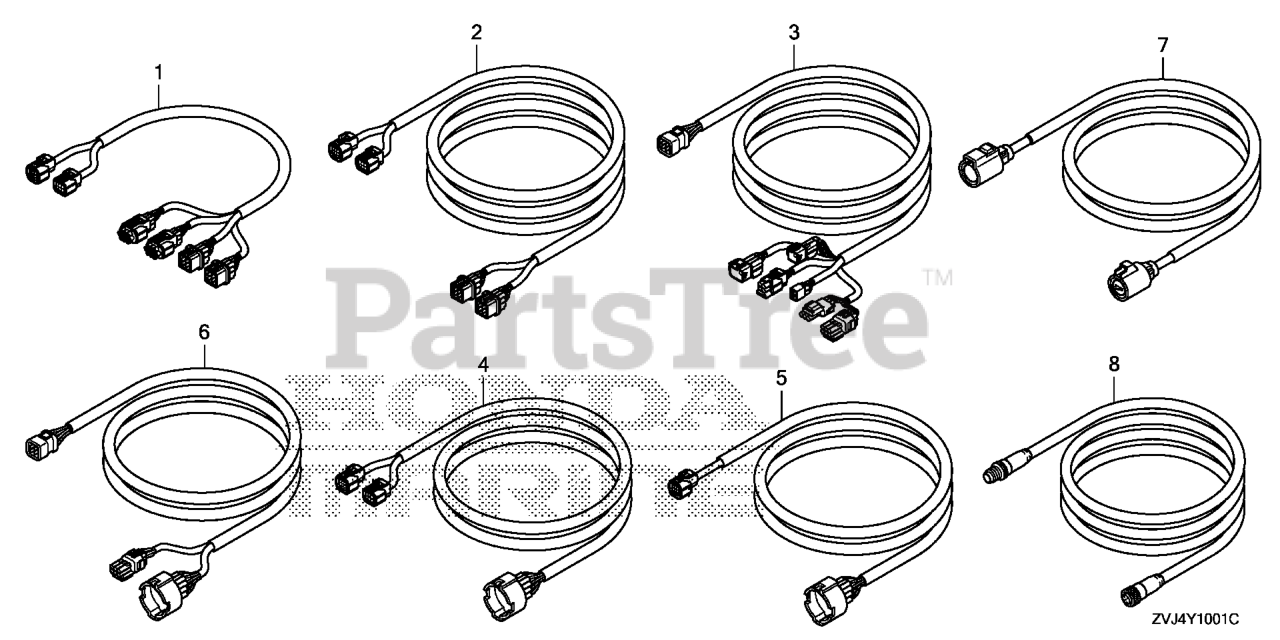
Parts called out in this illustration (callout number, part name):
1	CABLE ASSY., BRANCH
2	CABLE ASSY., TRUNK (18FT) (DBW)
2	CABLE ASSY., TRUNK (24FT) (DBW)
2	CABLE ASSY., TRUNK (30FT) (DBW)
4	CABLE ASSY., ENGINE DROP (SINGLE 6FT)
4	CABLE ASSY., ENGINE DROP (SINGLE 16FT)
4	CABLE ASSY., ENGINE DROP (SINGLE 20FT)
4	CABLE ASSY., ENGINE DROP (SINGLE 25FT)
4	CABLE ASSY., ENGINE DROP (SINGLE 30FT)
5	CABLE ASSY., ENGINE DROP (6FT)
5	CABLE ASSY., ENGINE DROP (10FT)
5	CABLE ASSY., ENGINE DROP (14FT)
7	WIRE ASSY., EXTENSION POWER
8	CABLE ASSY., NETWORK (6FT)
8	CABLE ASSY., NETWORK (16FT)
8	CABLE ASSY., NETWORK (32FT)
8	CABLE ASSY., NETWORK (49FT)
